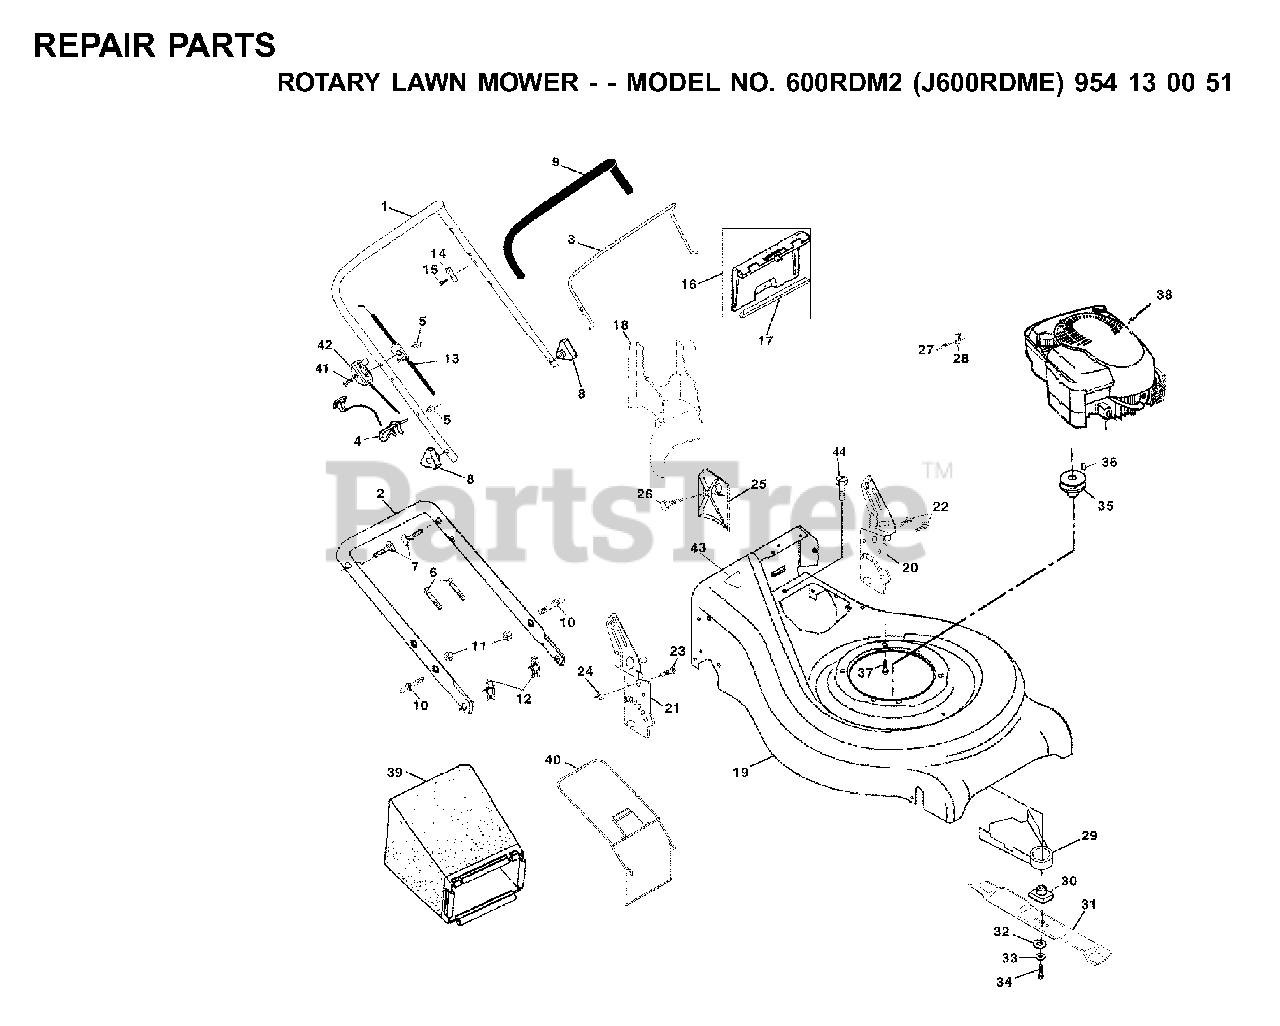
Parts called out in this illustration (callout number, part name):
2	HANDLE
3	CONTROL BAR
4	ROPE GUIDE
5	NUT
6	TIE GUIDE
7	HANDLE BOLT
9	GRIP.HANDLE.FOAM
10	BOLT
11	NUT
12	HAIRPIN COTTER
13	ENGINE ZONE CONTROL
14	BRACKET UPSTOP
15	SCREW.HEX.HEAD.WASHER.10-16
16	REAR DOOR KIT
17	SEALING
18	MULCH PLUG
20	.RACKET
22	SELF-TAPPING SCREW 5/16-18X3/4
23	BOLT, HEX HEAD 5/16-18
25	CLIPPING DEFLECTOR
27	SCREW.HEX.HEAD.WASHER.10-16
28	CABLE CLAMP(ENGINE)
29	DEBRIS SHIELD
30	RP BLADE ADAPTOR
31	21" MULCH BLADE PREMIUM
32	WASHER,HARDEN
33	LOCKWASHER
34	SCREW, HEX HD 3/8-24 X 1-3/8
35	ENGINE.PULLEY.FWG
36	HI PRO KEY PM
37	BOLT 3/8-16X1-1/8
40	GRASS CATCHER FRAME
41	SCREW 1/4-20 X 2.12
42	THROTTLE TRIGGER
43	DECAL MOWER CUT/FINGER
